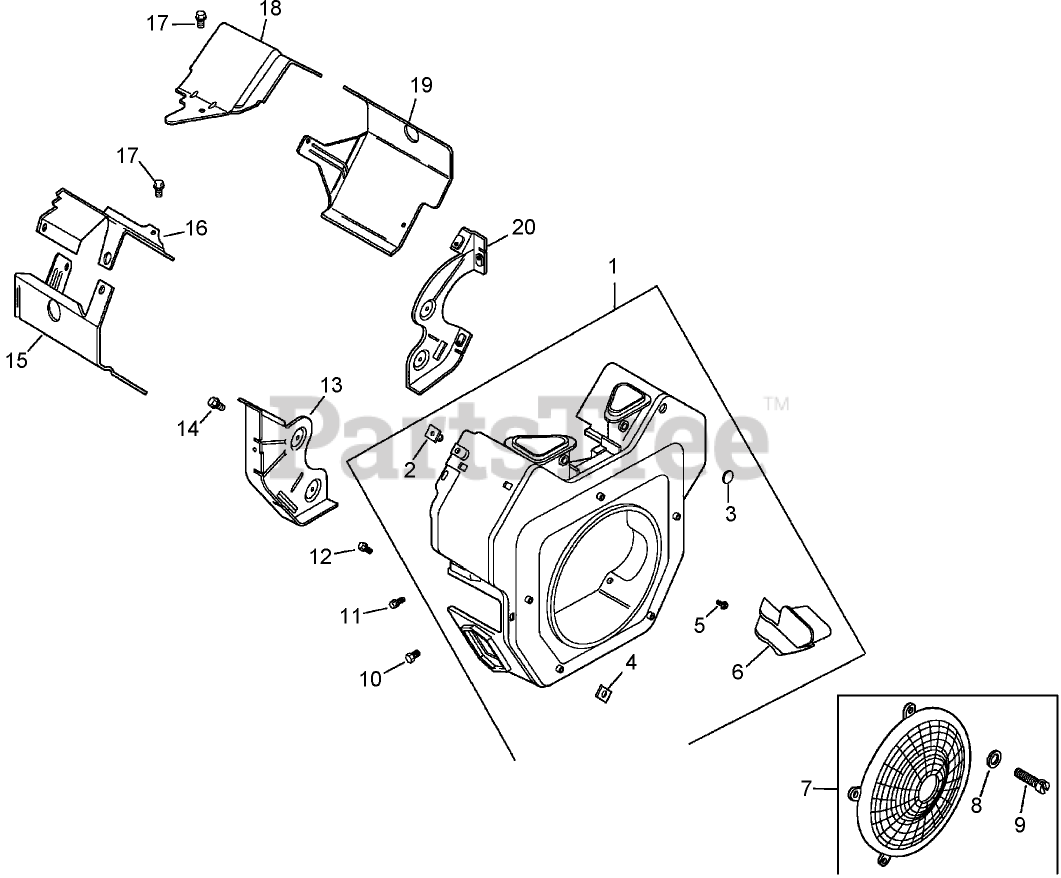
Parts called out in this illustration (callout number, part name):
1	Blower Housing ASM (Includes 2-6, and insert 24 332 01-S)
2	PLUG-BUTTON (9/16)
3	Nut-Plastic
4	NUT-PLASTIC
5	Screw-WSH HD Tap (8-18X.50)
6	Cover-Housing, Blower
7	Fixed Guard Kit (Includes 8, 9, and insert 24 332 01-S)
8	Washer-plain (1/4)
9	SCREW-LBD SOCKET PAN, M5X0.8X10
10	Screw-Hex Flange, Heavy (M5x0.8x16)
11	SCREW-FLANGE, THREAD FORMING (M5X0.8X16)
12	SCREW-FLANGE, THREAD FORMING (M5X.8X20)
13	Plate-Backing (No. 2 Side)
14	SCREW-FLANGE, THREAD FORMING (M6X1.0X16)
15	Baffle-Barrel, Cylinder (No. 2 Side)
16	BAFFLE-VALLEY (No. 2 SIDE)
17	SCREW-HHFTF (M5X.80X10)
18	BAFFLE-VALLEY (No. 1 SIDE)
19	Baffle-Barrel, Cylinder (No. 1 Side)
20	Plate-Backing (No. 1 Side)
